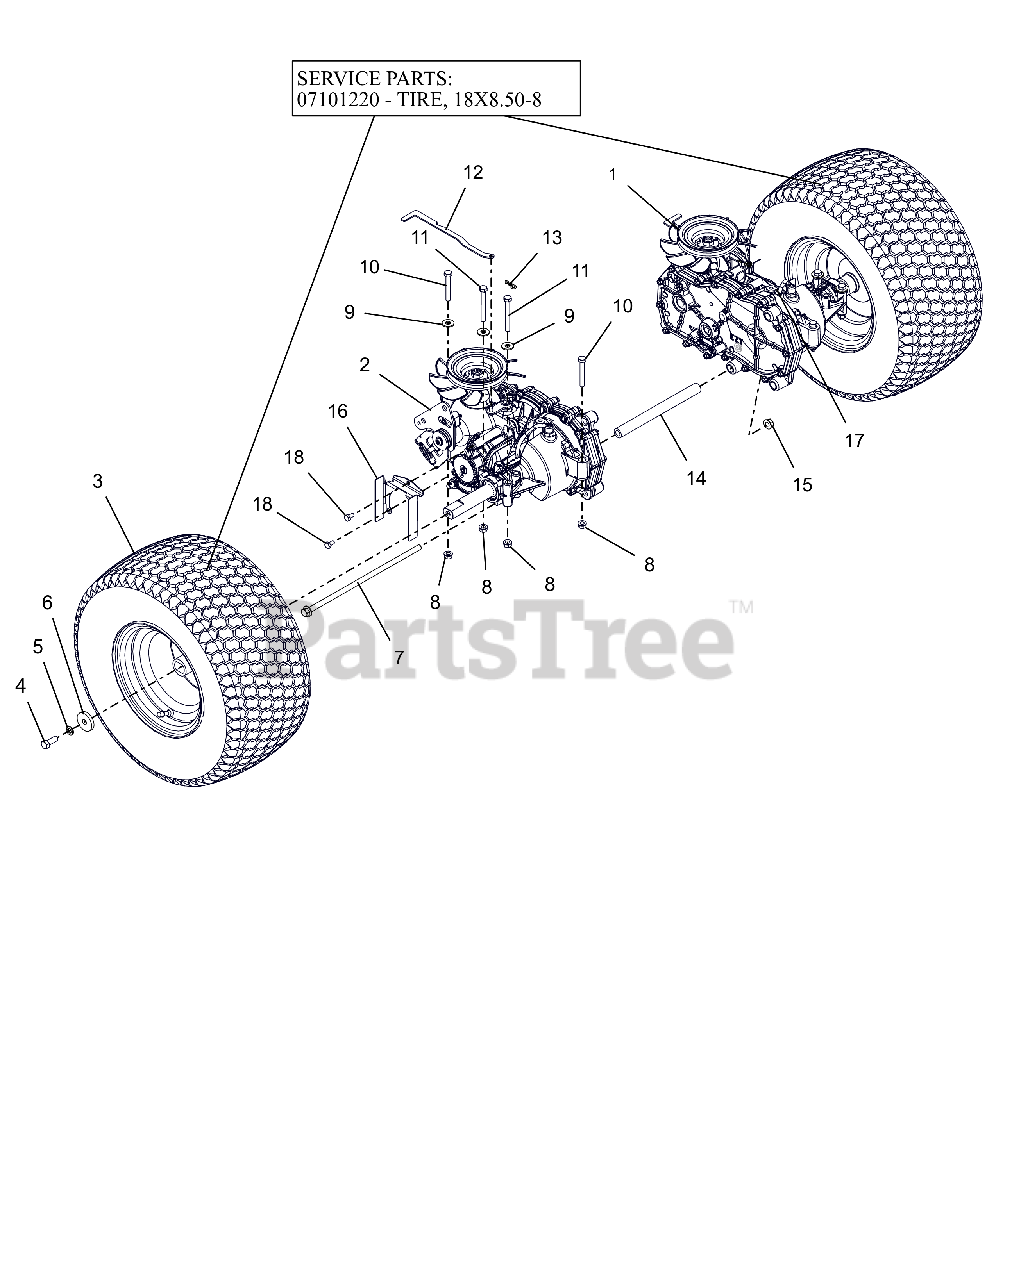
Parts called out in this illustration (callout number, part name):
1	TRANSAXLE EZT D-SHFT SHORT
2	TRANSAXLE EZT D-SHFT SHORT
3	ASM, WHL/TIRE 18X8.50-8 DHUB
3	TIRE, 18X8.50-8
4	BLT, HEX .38-16X1.00 G8ZCCEP30
5	WSHR,LK-REG .375X.094 ZCC
6	WSHR, FLT .406X1.50X.245 ZCC
7	BLT,HEX-FLG .38-16X11.5 G5 ZCC
8	NUT,LK-CTR-FLG .31-18 GF ZCC
9	WSHR,FLT .375X.875X.083 ZCC
10	BLT, HEX .31-18X2.25 G5 ZCC
11	BLT, HEX .31-18X2.75 G5 ZCC
12	BRKT, DUMP VALVE
13	PIN, HAIR #213 .08X1.19 ZCC
14	TUBE, TRANSAXLE BRACE 8.18LG
15	NUT-LK-CTR-FLG .375-16 GF ZCC
16	GUARD, PARKING BRAKE RH
17	GUARD, PARKING BRAKE LH
18	BLT,HEX .25-20X.50 G5 ZCC
